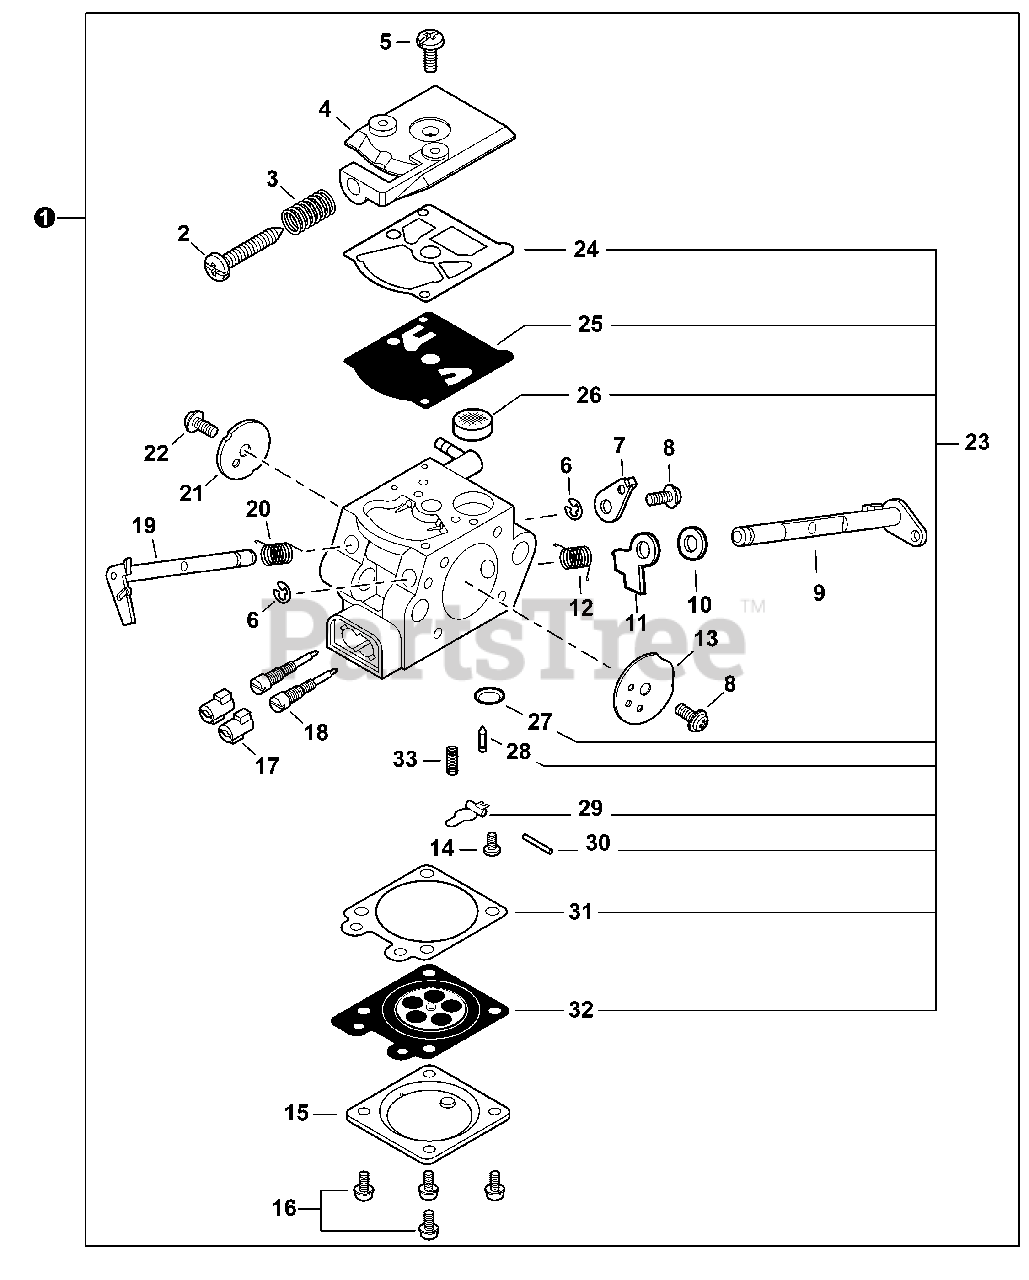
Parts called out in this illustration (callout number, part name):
1	CARBURETOR - WT-739
2	SCREW, IDLE ADJUST
3	SPRING, IDLE ADJUST
4	COVER ASSY, PUMP
7	LEVER, THROTTLE
9	SHAFT, CHOKE
11	LEVER, FAST IDLE
12	SPRING, CHOKE RETURN
13	VALVE, CHOKE
14	SCREW, METERING LEVER PIN
15	COVER, METERING DIAPHRAGM
17	CAP, LIMITER
18	NEEDLE, MIXTURE
19	SHAFT, THROTTLE
20	SPRING, THROTTLE RETURN
21	VALVE, THROTTLE
23	REPAIR KIT
24	GASKET, PUMP
25	DIAPHRAGM, PUMP
26	SCREEN, FUEL INLET
27	PLUG, WELCH
28	VALVE, INLET NEEDLE
29	LEVER, METERING
30	PIN, METERING LEVER
31	GASKET, METERING DIAPHRAGM
32	DIAPHRAGM, METERING
33	SPRING, METERING LEVER
